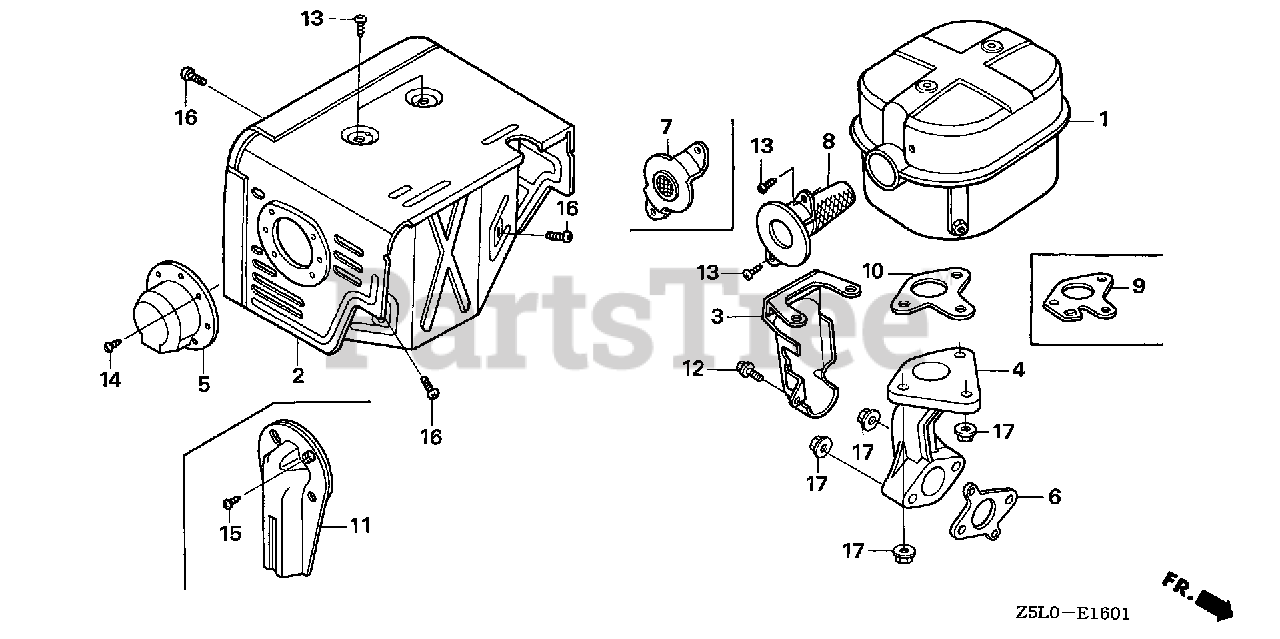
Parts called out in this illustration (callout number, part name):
2	PROTECTOR, MUFFLER
6	GASKET, EX. PIPE
8	ARRESTER, SPARK
9	GASKET, MUFFLER (ARRESTER) (NIPPON LEAKLESS)
13	SCREW, TAPPING (5X8)
16	SCREW, PAN (6X6)
17	NUT, FLANGE (8MM)
